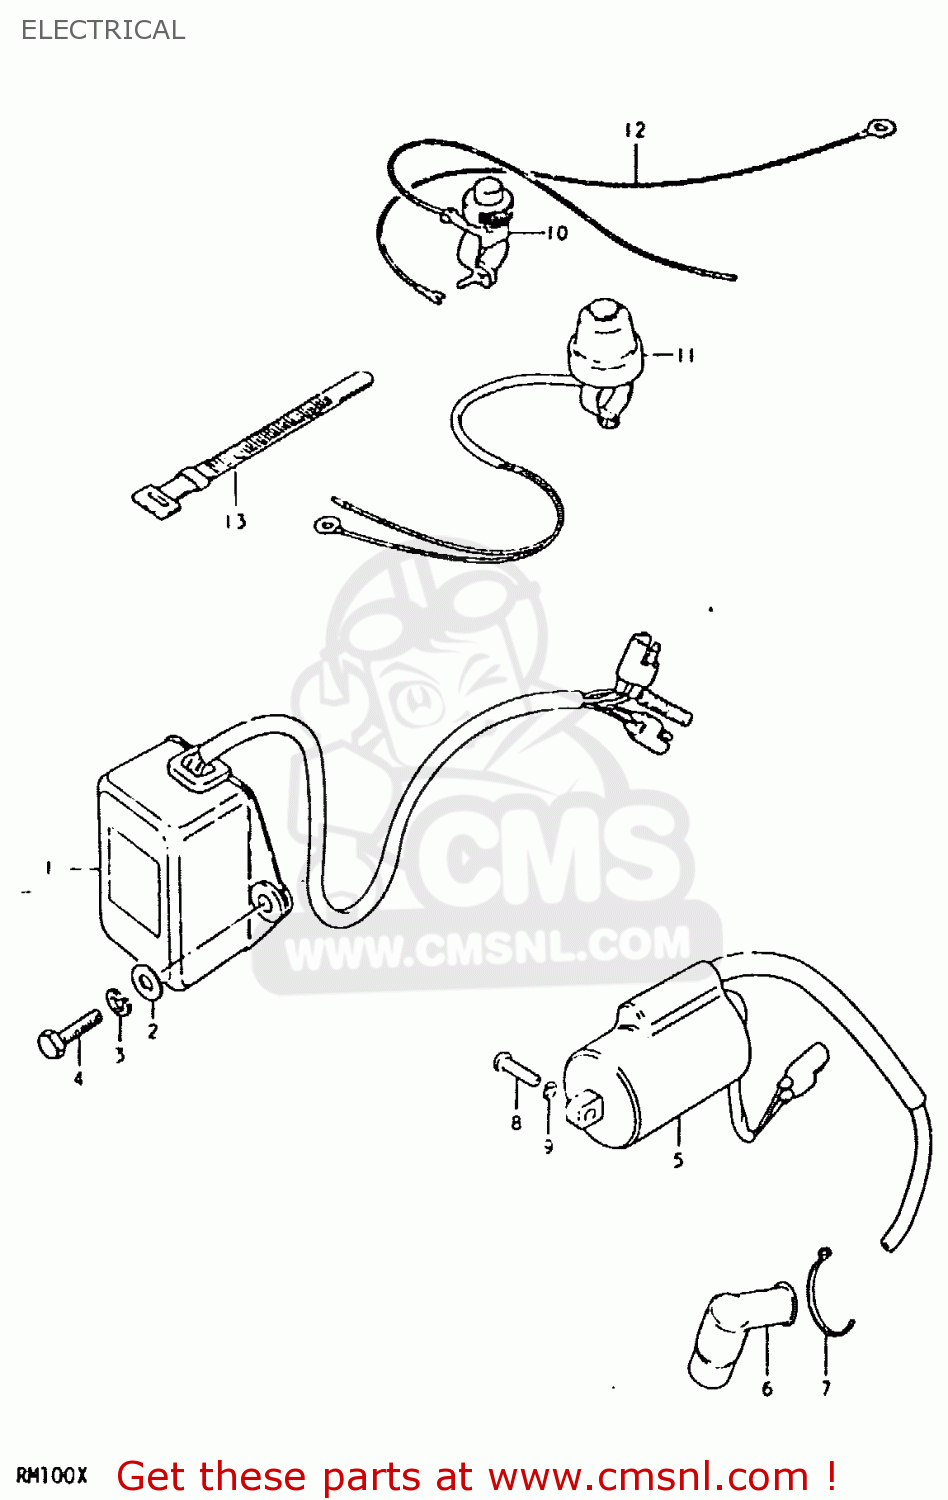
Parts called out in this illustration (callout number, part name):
1	CDI UNIT ASSEMBLY
2	WASHER(6.5X16X1.2)
3	LOCK WASHER
4	BOLT
5	COIL ASSEMBLY,IGNITION
6	CAP,SPARK PLUG
7	BELT
8	SCREW 5X20
9	LOCK WASHER
10	SWITCH ASSEMBLY
11	SWITCH ASSEMBLY
12	WIRE,ENGINE STOP EARTH
13	CLAMP(L:120)
